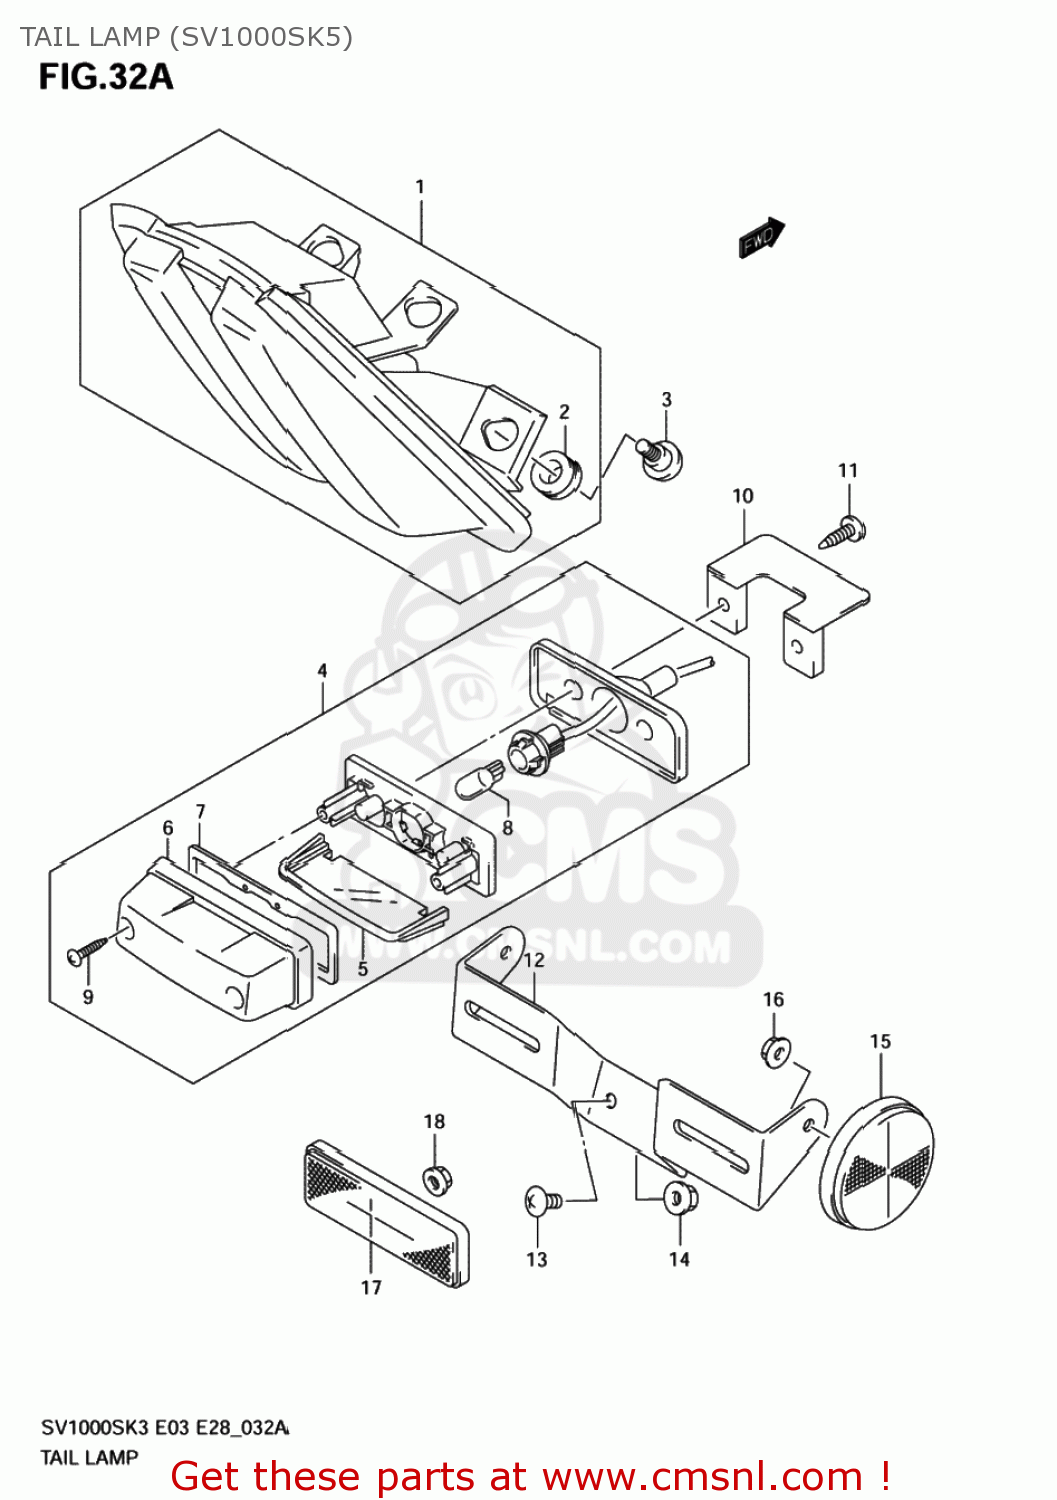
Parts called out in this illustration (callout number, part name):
1	LAMP ASSY,RR COMBINATION
2	CUSHION
3	SCREW(6X22.5)
4	LAMP ASSY,LICENSE
5	LENS
6	COVER
7	GASKET (NAS)
8	BULB(12V5W)
9	SCREW
10	BRACKET,LICENSE
11	SCREW
12	BRACKET,LICENSE PLATE
13	SCREW
14	NUT
15	REFLECTOR ASSY,RR SIDE
16	NUT
17	REFLECTOR ASSEMBLY,REAR
18	NUT
